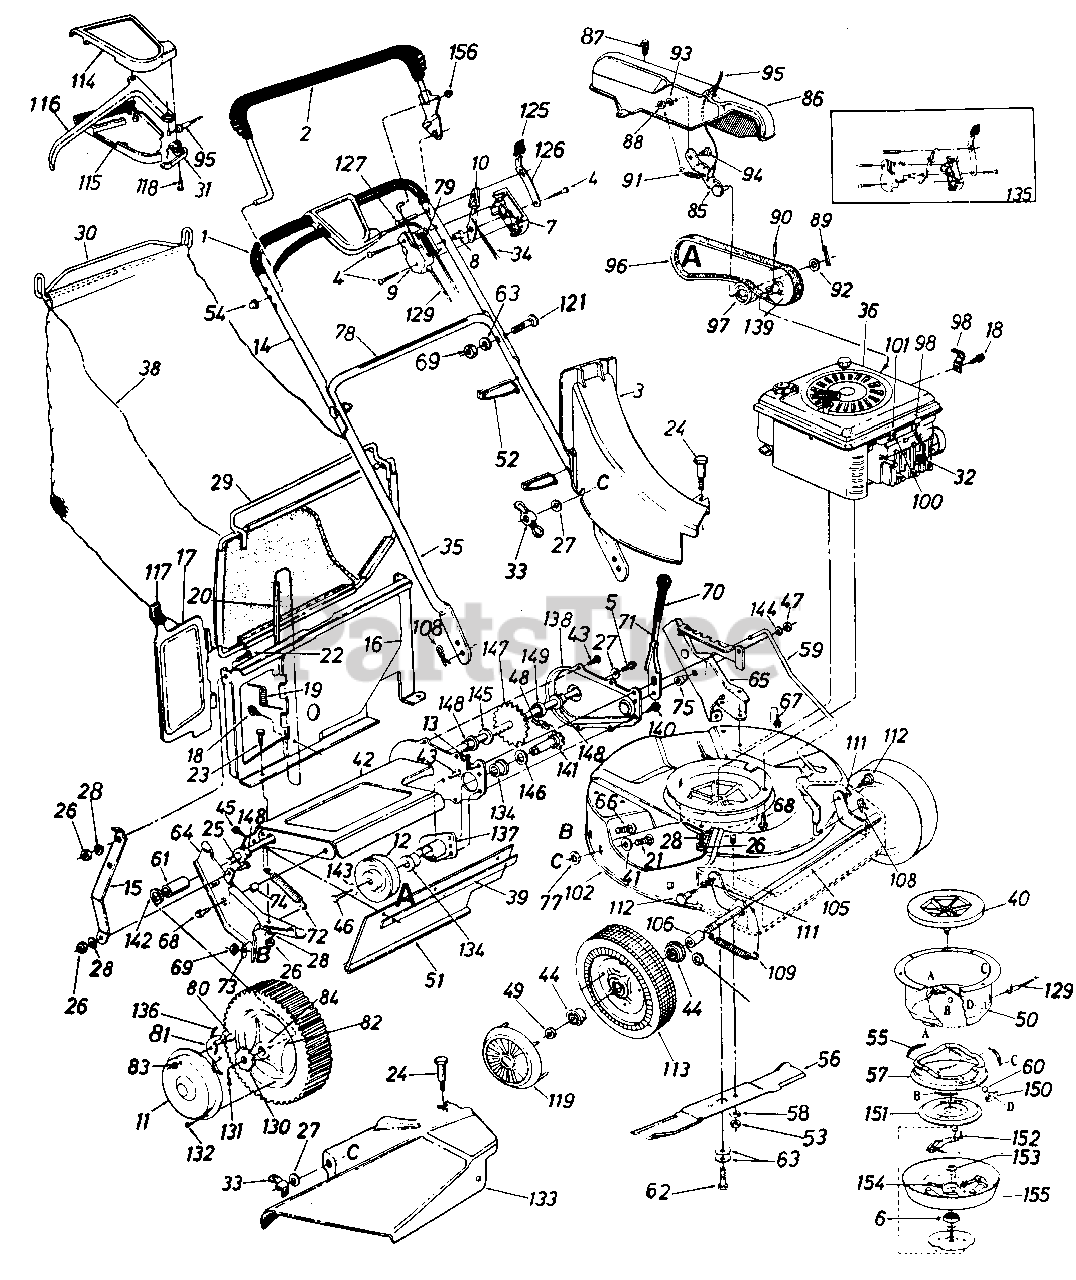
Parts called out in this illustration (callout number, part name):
1	GRIP-SHRINK-25 IN
3	CHUTE ASSY-TOP DISCH
4	SCREW-TRUSS MACH
5	SCREW-HEX HD TAP 1/4-20 X 7.5
6	BEARING-BALL
7	PANEL HALF-CONTROL
8	PIN-CONTROL DISC
9	PANEL HALF-CLUTCH
10	LEVER-THROTTLE CONT-REV
11	HUB CAP
12	PULLEY-1/2 V
13	PIN-COTTER-3/32 DIA X .75
14	HANDLE-UPPER-CHROME
15	BRACKET-PANEL SUP
16	PANEL ASSY-CATCHER
17	DOOR-TOP DISCHARGE
18	SCREW-HEX B-TAP #10 X .38
19	SPRING-TORSION
21	BOLT-CARRIAGE 1/4-20 X .62
22	SCREW-TRUSS MACH 1/4-20 X 1.00
23	SCREW-HEX 1/4-20 X .50
24	SCREW-SHLD
25	SCREW-HEX 1/4-20 C .62
26	NUT-HEX 1/4-20
27	WASHER-SPRING BELL
28	LOCK WASHER 1/4 DIA
29	FRAME-FRONT
30	HANDLE-GRASSCATCHER
31	CAP-CABLE MTG
32	INSULATOR-SPARK PLUG
33	NUT-INS WING L-1/4-20
34	WIRE-THROTTLE 58 LG
35	HANDLE-LOWER PAINTED
38	BAG-GRASS-CONV
39	STRIP-RETAINING
40	ADAPTER-FAN
41	WASHER-FL-.344 ID X .62 OD X .033
42	AXLE ASSY-CHAIN
43	SCREW-HEX B-TAP 1/4 X .38
44	BEARING-BALL
45	SCREW-HEX WASH HD
46	SCREW-HEX WASH 1/4-20X.75
47	NUT-HEX LOCK 3/8-24
48	#48 CHAIN 1/2 PITCH
49	NUT-HEX INS L-1/2-20
50	HOUSING-CLUTCH
51	FLAP-RR
52	TIE-CABLE
53	NUT-HEX 3/8-24
54	NUT-SPEED
55	SPRING-EXTENSION
56	BLADE-21IN
57	CONE-BRAKE CUP
58	WASHER-LOCK-3/8
59	ROD-HGT ADJ 1.50 X 19.42
60	BALL-STEEL
61	SPACER-.513 ID X .703 OD X .69
62	SCREW-HEX 3/8-24 X 2.00
63	WASHER-BELL .400 ID X .88 X .060
64	BRACKET ASSY-HDLE-RH
65	BRACKET ASSY-HDLE-LH
66	BOLT-CARRIAGE 5/16-18 X .62
67	SCREW-HEX WASH HD 5/16-18X1/2
68	SCREW-HEX
69	NUT-HEX 5/16-18
71	LEVER-HGT ADJ
72	SPRING-EXTENSION
73	WASHER-BELL .337 X .867 X .057
75	SPACER-SHLD .500 X .100
77	RETAINER-BOLT 1/4X.50 OD
78	LABEL-BBC-INST
80	SCREW-SHLD .342 DIA X .268
81	PAWL
82	WHEEL ASSY W/TIRE-T-TREAD
83	NUT-INS LOCK 1/4-20
84	BEARING-BALL
85	BRACKET ASSY-IDLER
86	COVER-BELT
87	SCREW-HEX WASH SF TAPP
88	NUT-HEX 1/4-20
89	PIN-COTTER-1/8 DIA X 1.00
90	PIN-SPRING SPIR 3/16 X 1.00
91	SPRING-EXTENSION
92	WASHER-FL-.531 X .930 OD X .050
93	LOCK WASHER 1/4 DIA
94	SCREW-SHLD
95	CABLE-CLUTCH
96	BELT-V 1/2 X 32
97	PULLEY-IDLER-FLAT
98	CLAMP-CASING
100	SCREW-HEX WASH HD TAP
101	CLAMP-CASING
108	PIN-INTERN COT-5/16 DIA
109	SPRING-EXTENSION
111	WASHER-INTERN L 3/8 X.56 OD X .018
112	SCREW-SHLD .623 X .425
113	WHEEL ASSY W/TIRE
114	COVER-HALF-CONTROL
115	COVER-HALF CONT-LWR
116	LEVER-CONTROL
118	SCREW-FL C-SUNK AB
119	HUB CAP-BLACK
121	BOLT-CARRIAGE-CURV 5/16-18 X 1.38
125	KNOB
126	SPRING-LOCKOUT
127	PIN-LOCKING
129	CABLE-CLUTCH
130	RACHET-WHEEL
131	PIN-COTTER-1/8 DIA X 1.00
132	SCREW-PAN HD TAPP
133	DEFLECTOR ASSY
134	BUSHING-FL
135	KIT-THROTTLE CONTROL
136	SPRING-NYLON
137	FLANGE ASSY-BRG FL
138	CHAIN COVER-SP ASSY
139	PULLEY-ENGINE-1/2 V
140	SCREW-HEX WASH SF TAPP
141	SHAFT ASSY-SPROCKET
142	WASHER-FL-.531 X .930 OD X .050
143	WASHER-SPRING BELL
144	WASHER-FL-.385 ID X .87 OD X .06
145	WASHER-FL
146	WASHER-FL-.635 ID X 1.12 OD
147	SHAFT ASSY-REAR
148	BEARING-HEX FLANGE .506 ID
150	BALL-BLOCK
151	CONE-CLUTCH
152	SCREW-HEX WASH 1/4-20X.75
153	WASHER-FL .687 X 1.060 X .032
155	HOUSING-CLUTCH BLADE
